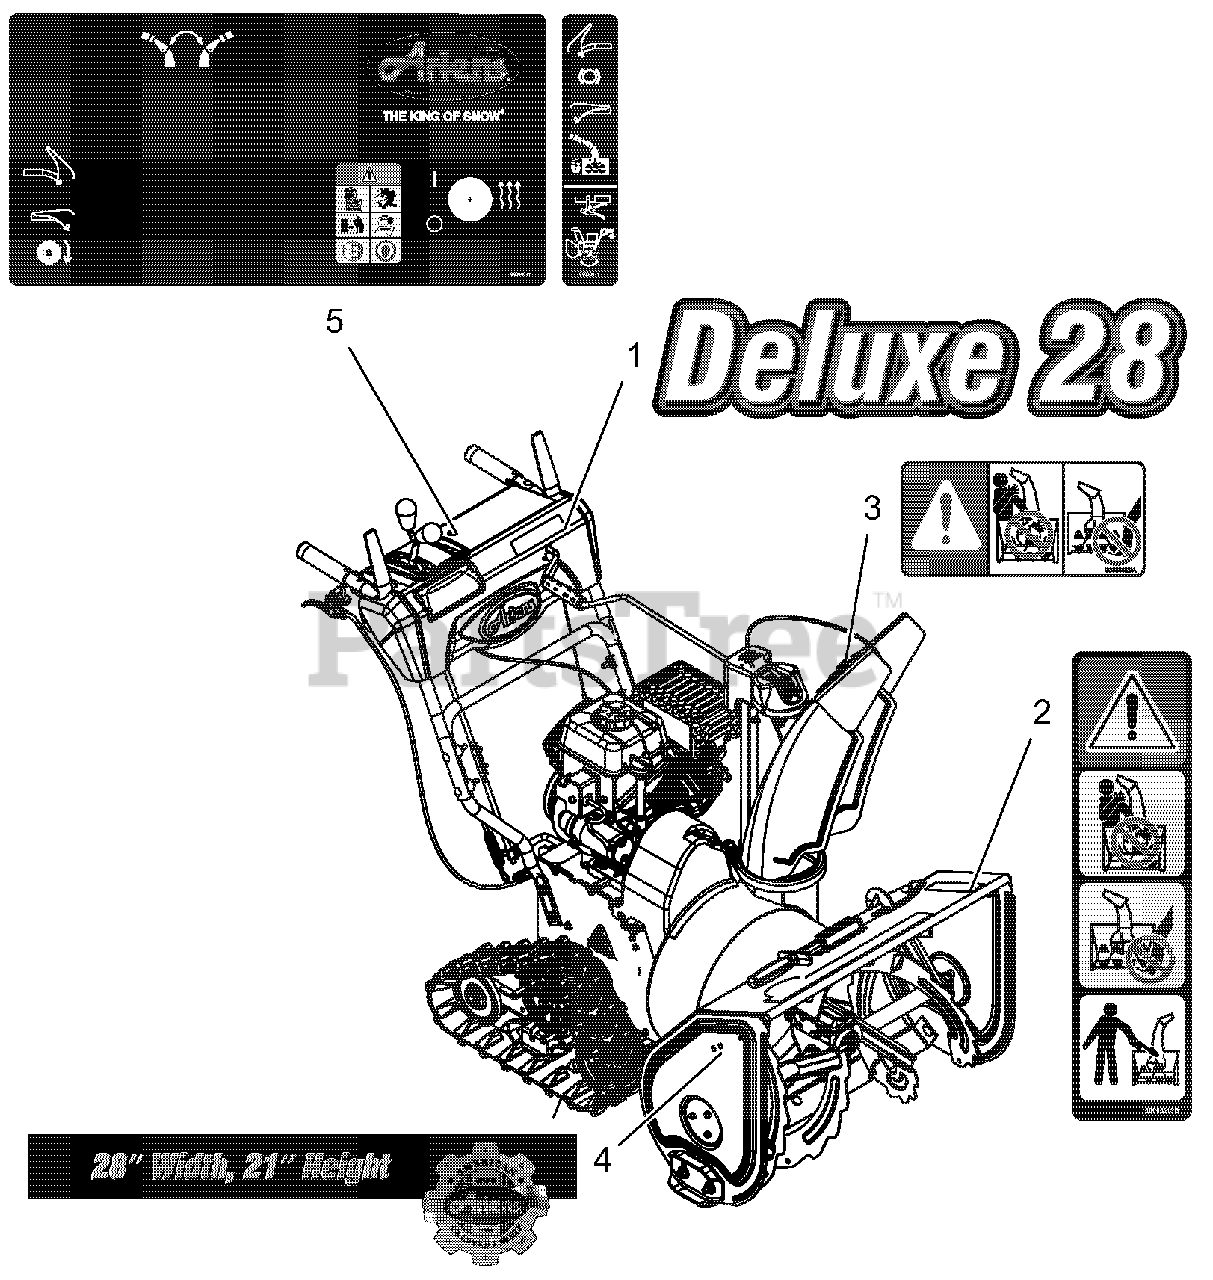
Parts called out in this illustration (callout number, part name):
1	DECAL, DELUXE 28 SM DASH
2	DECAL, DANGER - ROTATING PARTS
3	DECAL, DANGER
5	DECAL, CONTROL - DLX TRACK HW
